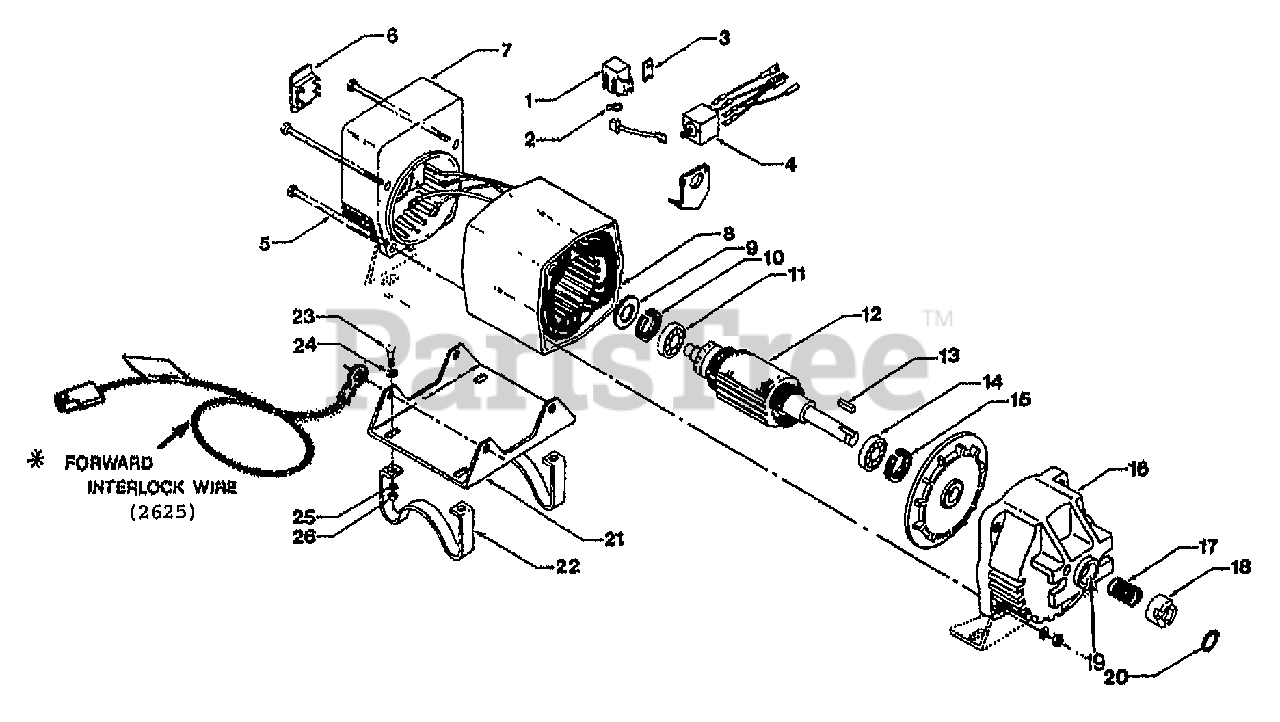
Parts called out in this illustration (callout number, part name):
2	D SPRING-BRUSH NLA @ DEPL
3	SHIM-BRUSH HOLDER
6	REGULATOR
9	OBS-WASHER 1.875X1.00
10	RING-TOLERANCE
11	BEARING-BALL
13	KEY-.188 SQX1.0
14	BEARING-BALL
15	RING-TOLERANCE
17	SPRING (TC)
18	KIT-CLUTCH DOGS TILLER
20	RING-RETAIN EXT .707 ID
21	BRKT-MOUNTING GENERATOR
22	BRKT-LEG MOUNTING
23	SCR-HHC 5/16-18X.75 GR 5 ZP
24	WASHER-FLAT 5/16 SAE
25	WASHER-LK .312 ZP
26	NUT-HEX 5/16-18 ZP
